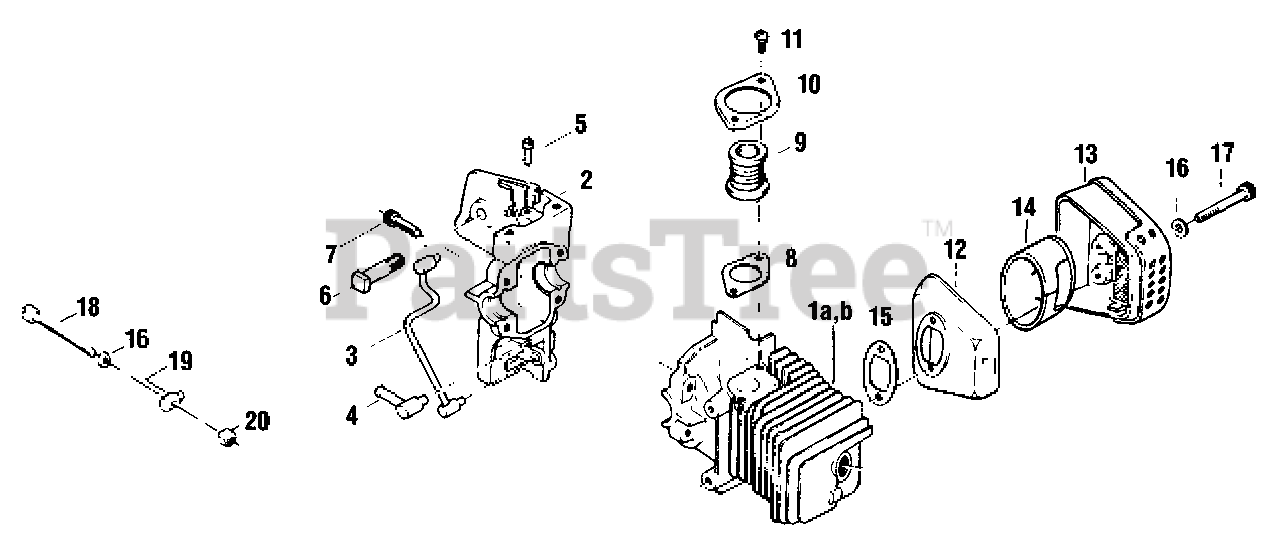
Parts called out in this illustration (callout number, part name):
1A	CYLINDER
1B	CYLINDER
2	CRANKCASE
3	TUBE, CRANKCASE OIL
4	ELBOW
5	PULSE JOINT
6	BOLT, BAR
7	SCREW - 5X18
8	GASKET
9	BOOT
10	BRACKET, BOOT
11	SCREW - 4X14
12	MUFFLER BASE
13	COVER, MUFFLER
14	MUFFLER PIPE
15	GASKET, EXHAUST
16	WASHER - 5
17	SCREW - 5X45
18	SCREW, ADJUST
19	STUD, ADJUST
20	LOCKNUT
